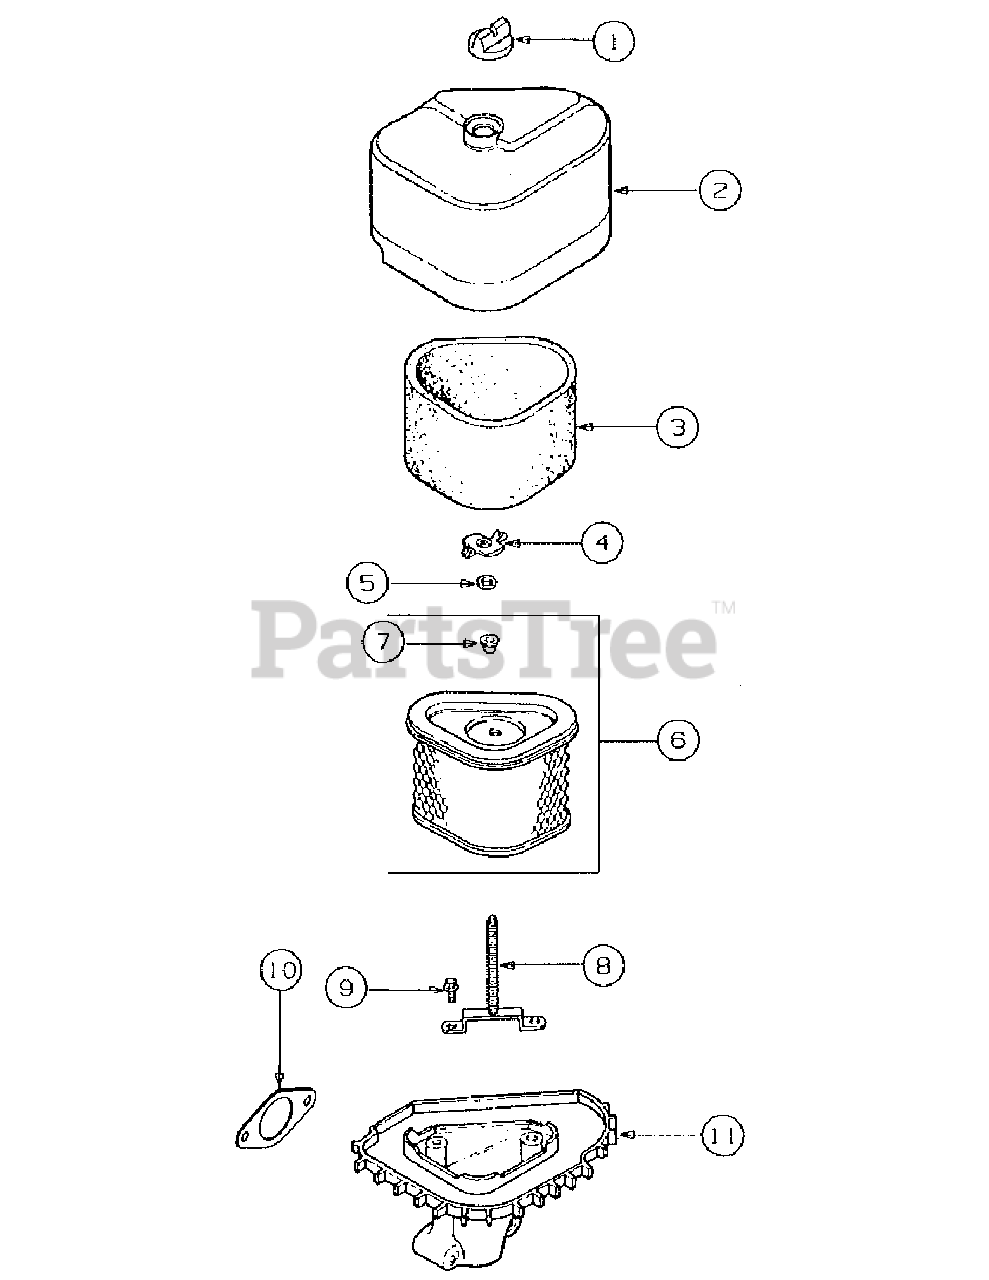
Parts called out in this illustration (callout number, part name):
1	Knob, Air Cleaner Cover
2	Cover, Air Cleaner
3	Precleaner, Element
5	Washer, Plain 1/4
6	Element, Air Cleaner
8	Stud, Mtg Plate
9	Screw, Mtg Plate Stud
10	Gasket, Air Cleaner
11	Base, Air Cleaner
